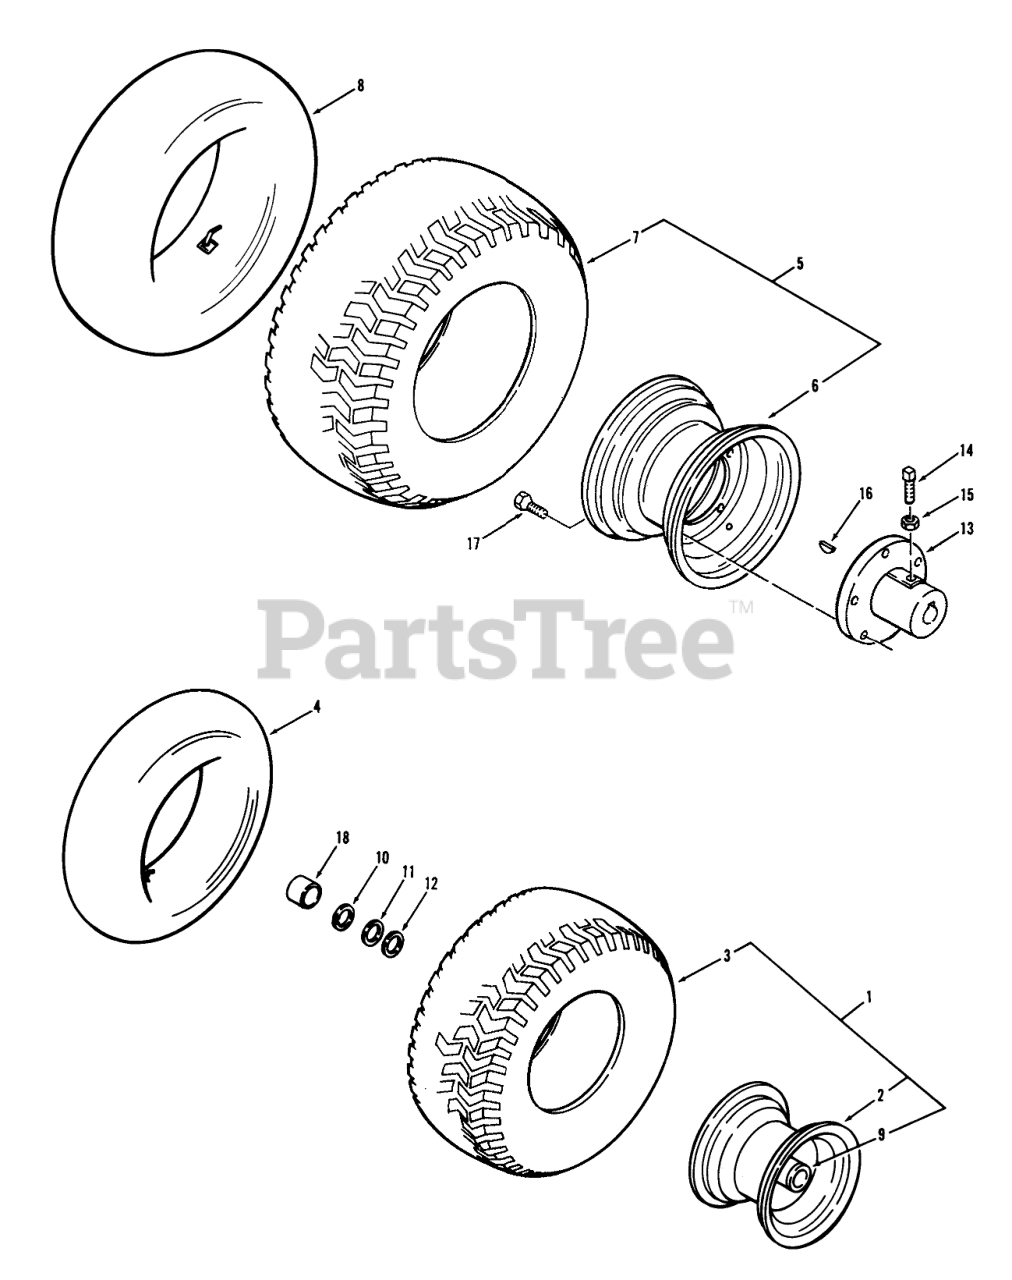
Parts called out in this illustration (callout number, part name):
1	ASSY-WHEEL & TIRE
2	WHEEL ASSY
3	TIRE TURF SAVER 16X6.50-8
4	Tube
5	Wheel and Tire
5	Tire & Wheel Assy
6	Wheel
7	Tire
7	TIRE 22 X 7.50-12
8	TUBE-INNER
9	Bearing
10	Snap Ring
11	WASHER
12	WASHER-SHIM
13	Hub Rear
14	Screw-Set
15	Nut
16	KEY-WOODRUFF
17	Lug Nut
18	HUB CAP
